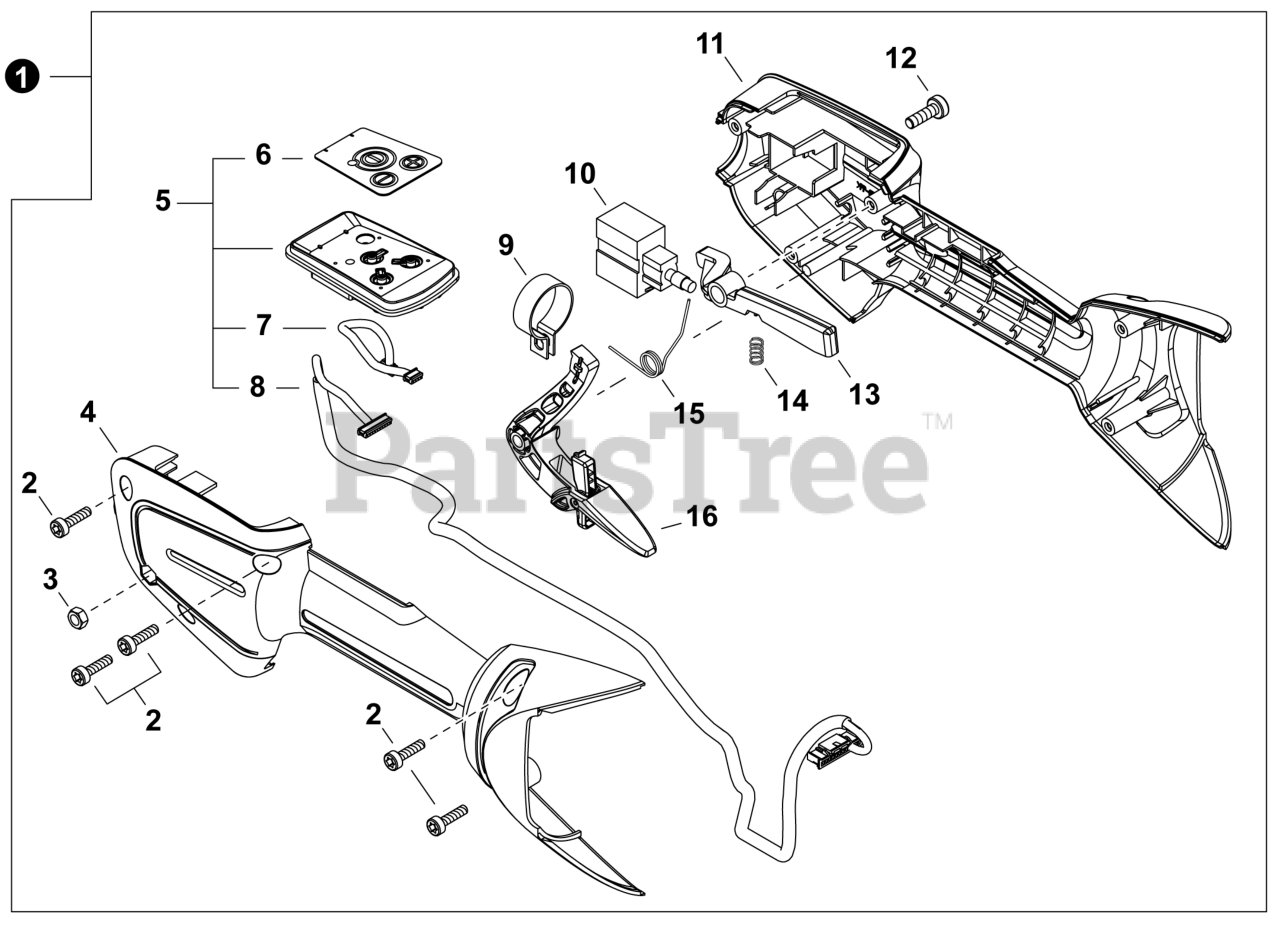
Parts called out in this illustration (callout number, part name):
1	CONTROL HANDLE ASSY
2	BOLT, TORX 4x16
4	GRIP, HANDLE - LEFT
5	SWITCH ASSY, ON-OFF
6	LABEL - SWITCH
7	HARNESS, WIRE - SWITCH
8	HARNESS, WIRE - MAIN
10	SWITCH, SPEED CONTROL
11	GRIP, HANDLE - RIGHT
12	BOLT, TORX 5x16
13	LOCKOUT, THROTTLE
14	SPRING, COIL
15	SPRING, TORSION
16	TRIGGER ASSY, THROTTLE
